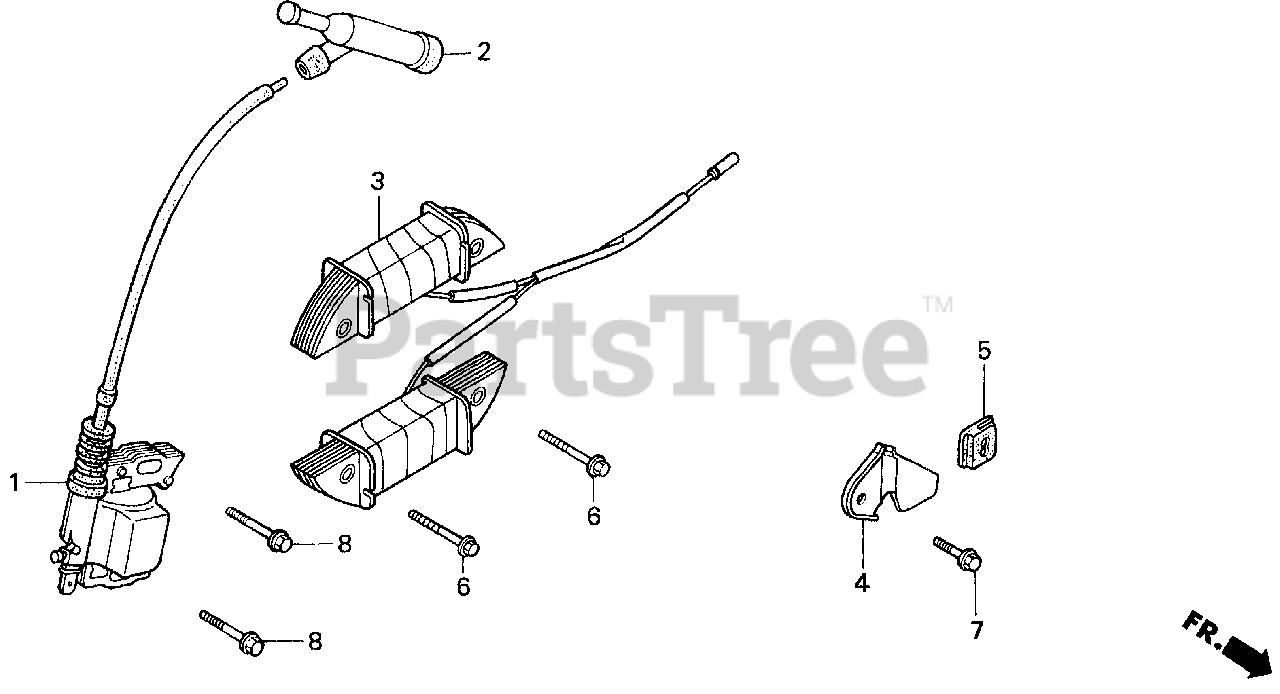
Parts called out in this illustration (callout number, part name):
1	COIL ASSY., IGNITION
2	CAP ASSY., NOISE SUPPRESSOR
8	BOLT, FLANGE (6X25)
